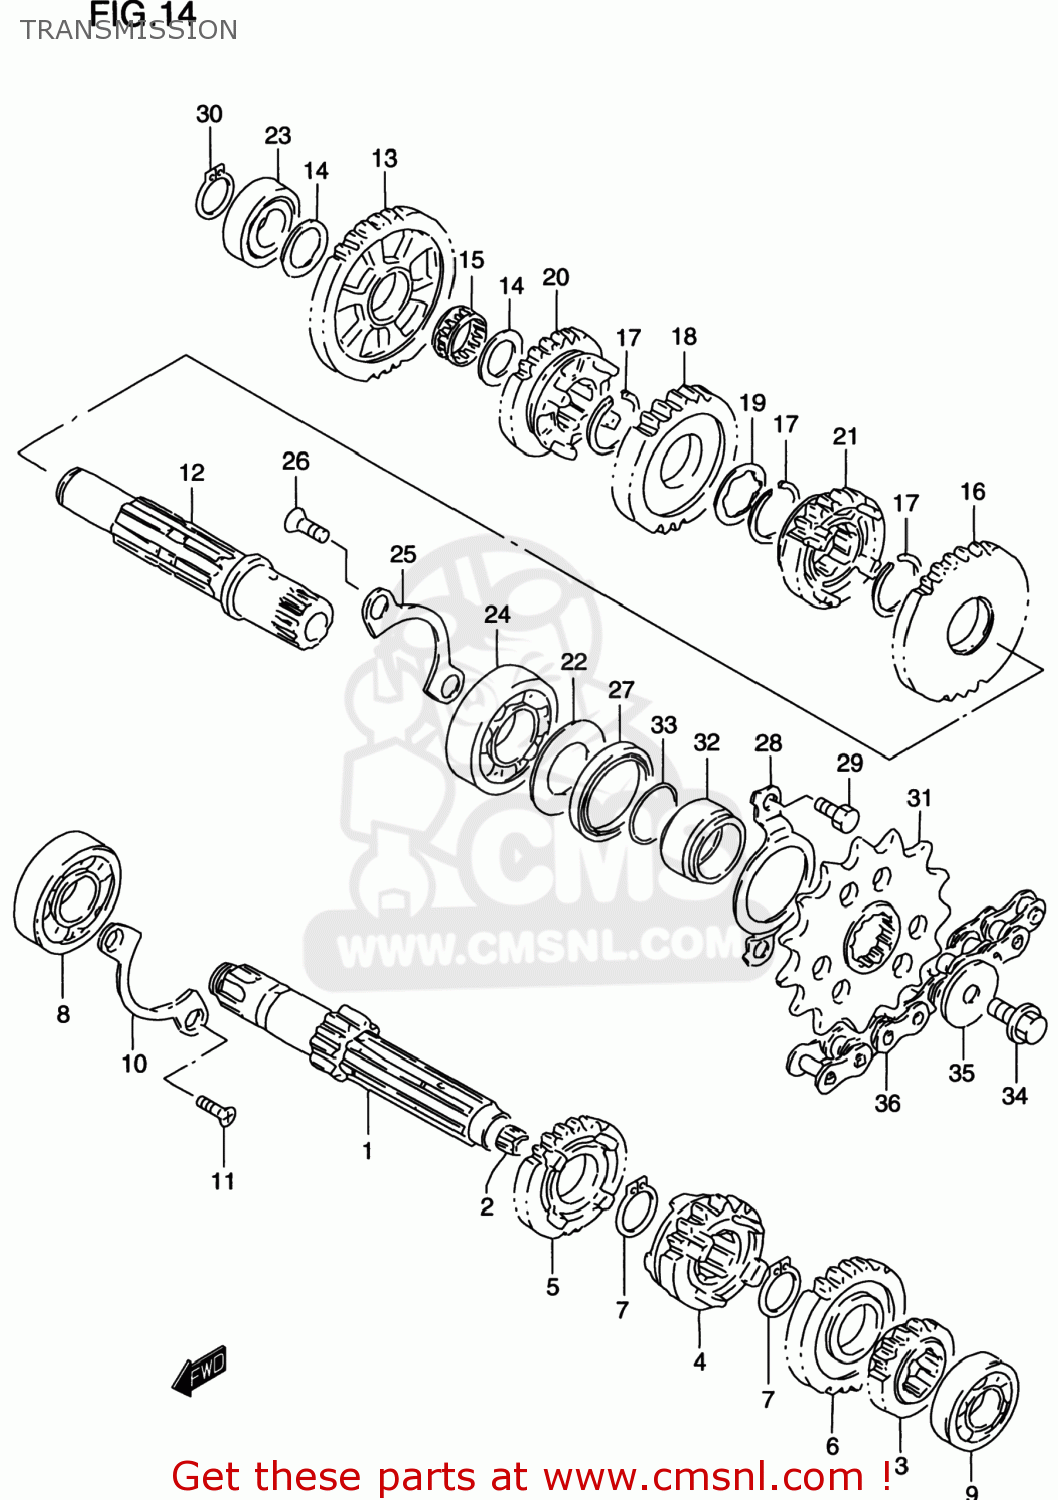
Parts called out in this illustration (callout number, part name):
1	SHAFT,COUNTER(NT:11)
2	BUSH
3	GEAR,2ND DRIVE
4	GEAR,3RD DRIVE(NT:16)
5	GEAR,4TH DRIVE
6	GEAR,FIFTH DRIVE
7	CIRCLIP
8	BEARING(20X47X14)
9	BEARING
10	RETAINER,DRIVE SHAFT BEARING
11	SCREW
12	SHAFT,DRIVE
13	GEAR,1ST DRIVEN
14	WASHER,THRUST
15	BEARING(17X21X9.8)
16	GEAR,2ND DRIVEN(NT:29)
17	CIRCLIP
18	GEAR,3RD DRIVEN(NT:23)
19	WASHER,LOCK
20	GEAR,4TH DRIVEN(NT:23)
21	GEAR,5TH DRIVEN
22	WASHER,OIL SEALING
23	BEARING(17X36X12)
24	BEARING(22X50X14)
25	RETAINER,DRIVE SHAFT BEARING
26	SCREW
27	SEAL,OIL(30X40X6)
28	RETAINER,DRIVESHAFT O
29	BOLT
30	CIRCLIP,17MM
31	SPROCKET,ENGINE
32	SPACER,ENGINE SPROCKET
33	O RING(D:2.5,ID:21)
34	BOLT
35	WASHER
36	CHAIN(DID520VC5,112LE)
